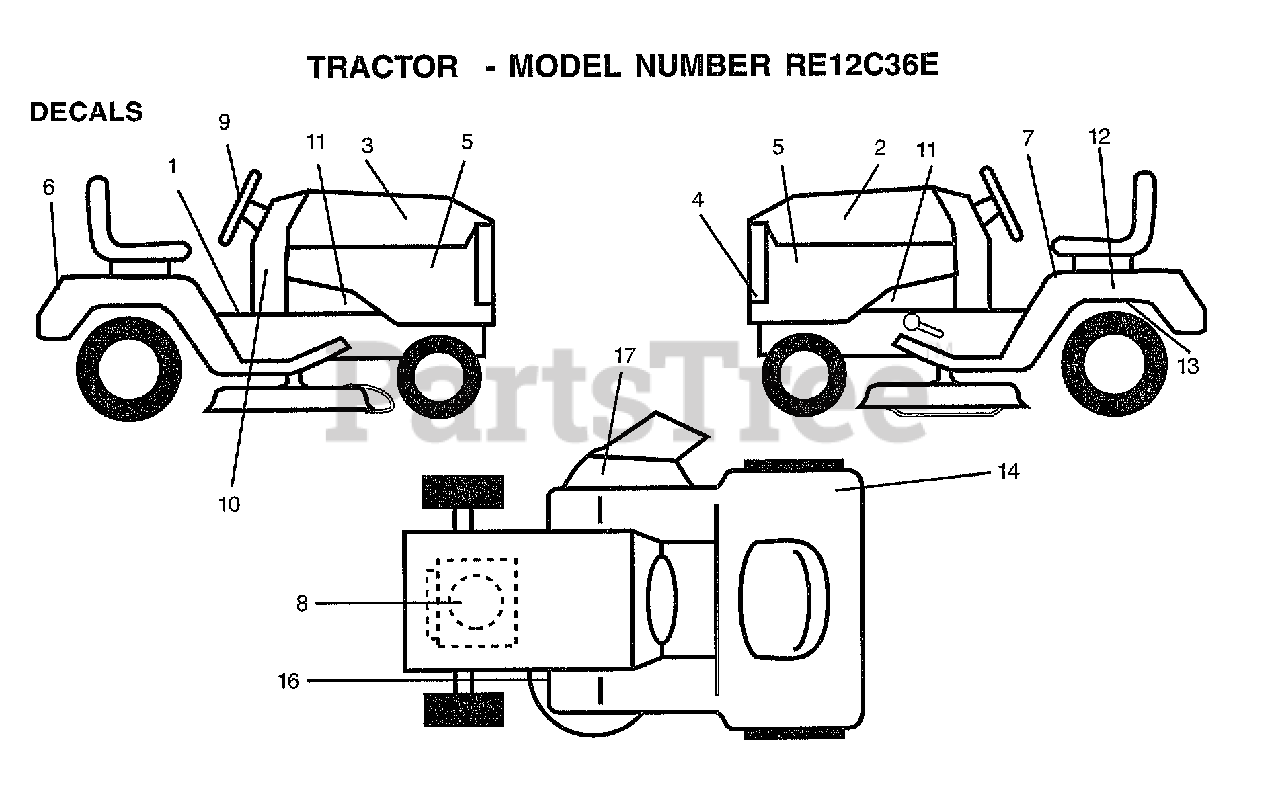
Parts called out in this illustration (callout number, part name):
1	DECAL CLUTCH/BRAK
2	DECAL HD RLY LH
3	DECAL HD RLY RH
4	GRILL DECAL
5	DECAL.INSERT.HOOD
6	FENDER DECAL
7	DECAL.READ.O.MANU
8	DECAL, ENGINE
9	"DECAL,STR WHL"
10	DECAL.EURO.ST.CE.
11	"DECAL CHASSIS,HOT"
12	DECAL.BATRY.3-3908
13	DECAL.DRAWBAR.LDL
16	DECAL.DANGER.CUTF
17	DECAL.V.BELT
